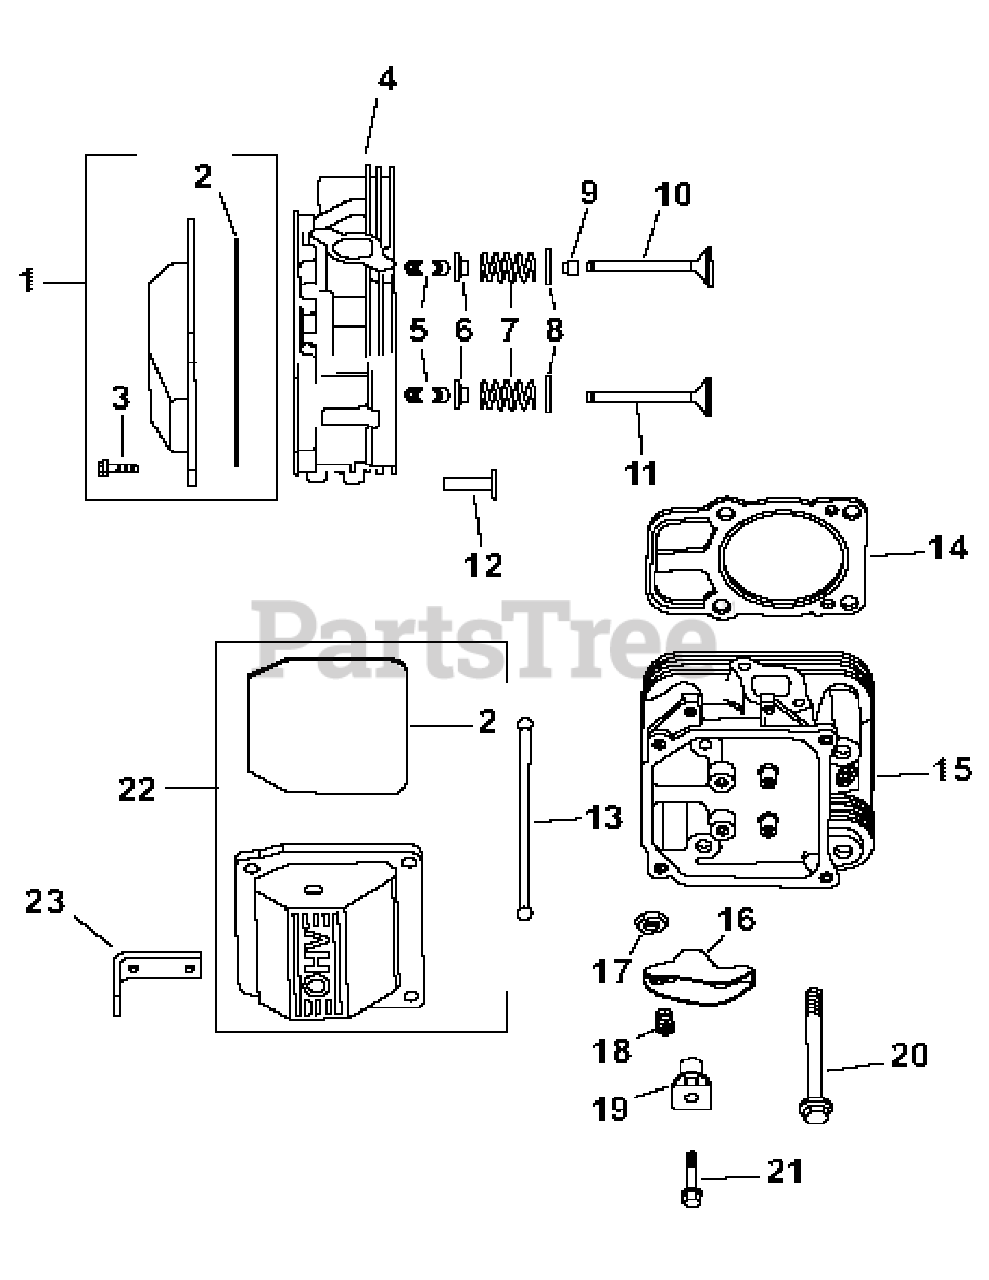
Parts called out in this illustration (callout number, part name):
1	Valve Cover Kit
2	O-Ring
3	Hex Flange Screw
4	Head Assembly # 1 Cylinder
5	Retainer Kit
6	Valve Spring Cap
7	Valve Spring
8	Spring Retainer
9	Valve Stem Seal
10	Intake Valve (Std.)
10	Intake Valve (.25)
11	Exhaust Valve (Std.)
11	Exhaust Valve (.25)
12	Tappet
14	Cylinder Head Gasket Kit
15	Head Assembly # 2 Cylinder
16	Rocker Arm
19	Rocker Arm Pivot
20	Hex Flange Screw
21	Hex Flange Screw
22	Valve Cover Breather Kit
23	Lifting Strap
